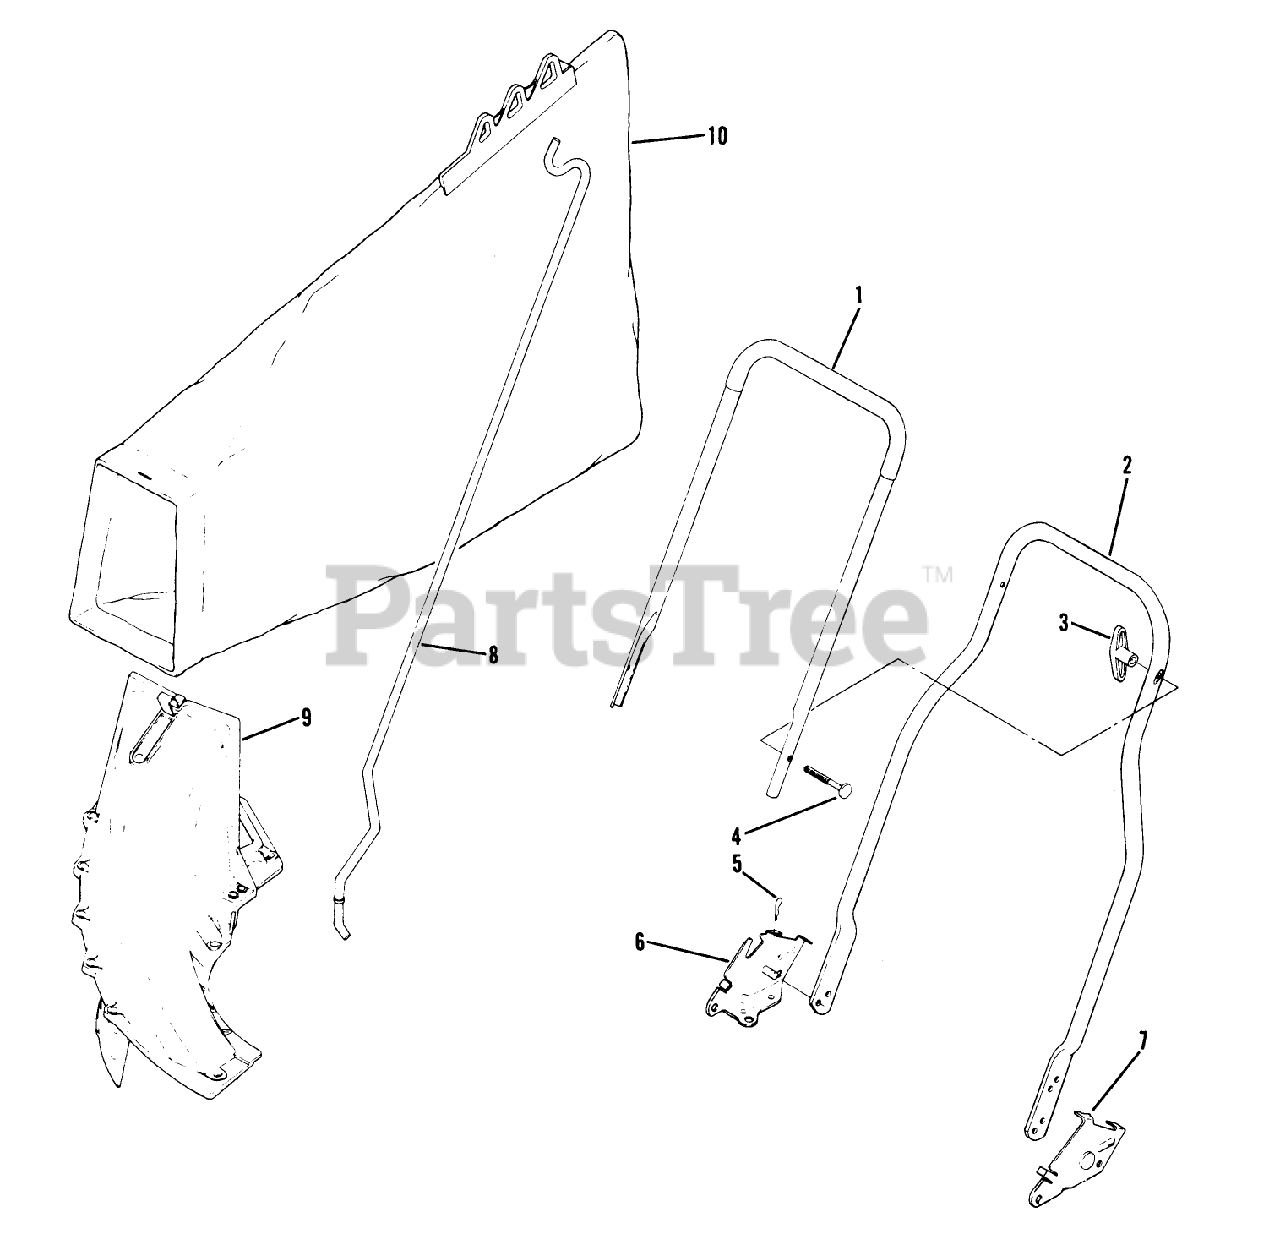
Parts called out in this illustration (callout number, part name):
3	NUT-WING
5	HAIR PIN
8	ROD GRASSBAG
10	89802 LB WHOLE GOODS
